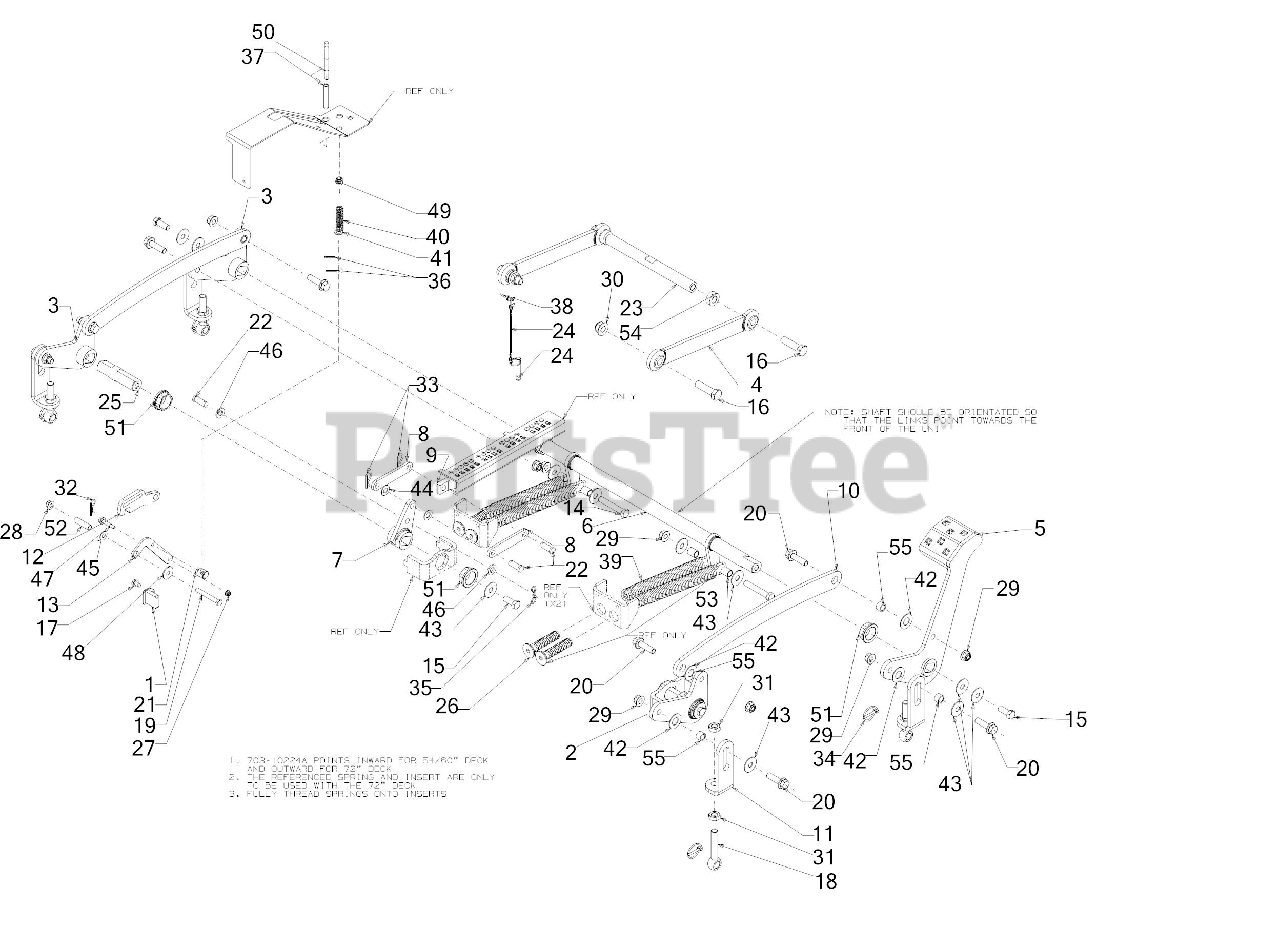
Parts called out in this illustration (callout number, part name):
1	LIFT LOCK MOUNT
2	DECK LIFT BELLCRANK ASSEMBLY (RH)
3	DECK LIFT BELLCRANK ASSEMBLY (LH)
4	FRONT DECK ROD ASSEMBLY
5	FOOT DECK LIFT BELLCRANK ASSEMBLY (RH)
6	FRONT DECK LIFT SHAFT
7	DECK LIFT HUB ASSEMBLY (LH)
8	DECK LIFT LINK
9	DECK LIFT LINK
10	DECK LIFT LINK
11	DECK LIFT LINK ARM ADJUSTER
13	PIVOT LOCKOUT LINK
14	HEX SCREW 1/2-13 x 3.00
15	SCREW 1/2-13 x 1.25 GR5
16	SCREW 5/8-11 x 2.25 GR5
17	SCREW 5/16-18 x .500
18	EYE BOLT 5/8-11 X 3.63
19	SCREW 3/8-16 x 2.75 GR5
20	BOLT-1/2-13X1.75LG
21	BRAKE FERRULE
22	CLEVIS PIN .500 x 1.25
23	FRONT LIFT SHAFT
24	DETENT PIN
25	LIFT SHAFT (LH)
26	SPRING INSERT SCREW
27	FLANGE LOCK NUT
30	FLANGE LOCK NUT
31	HEX NUT
32	INTERNAL COTTER PIN
33	COTTER PIN
35	PIN:COTTER
36	COTTER PIN 3/32
38	FULL TUBULAR RIVET
39	EXTENTION SPRING 1.20 x 11.35
40	COMPRESSION SPRING .656 ODX 2.445"
41	FLAT WASHER
42	FLAT WASHER .760ID X1.49OD x .06
43	WASHER .51 x 1.5 x .07
44	FLAT WASHER .510 x 1.00 x .060
45	FLAT WASHER
46	FLAT WASHER .510 x 1.000 x .125
47	SHOULDER SCREW
48	SHOULDER SPACER
49	BUSHING .380 ID
50	DECK LOCK OUT ROD
51	FLANGE BEARING
53	SPACER 0.535 X 0.68 X 0.83
